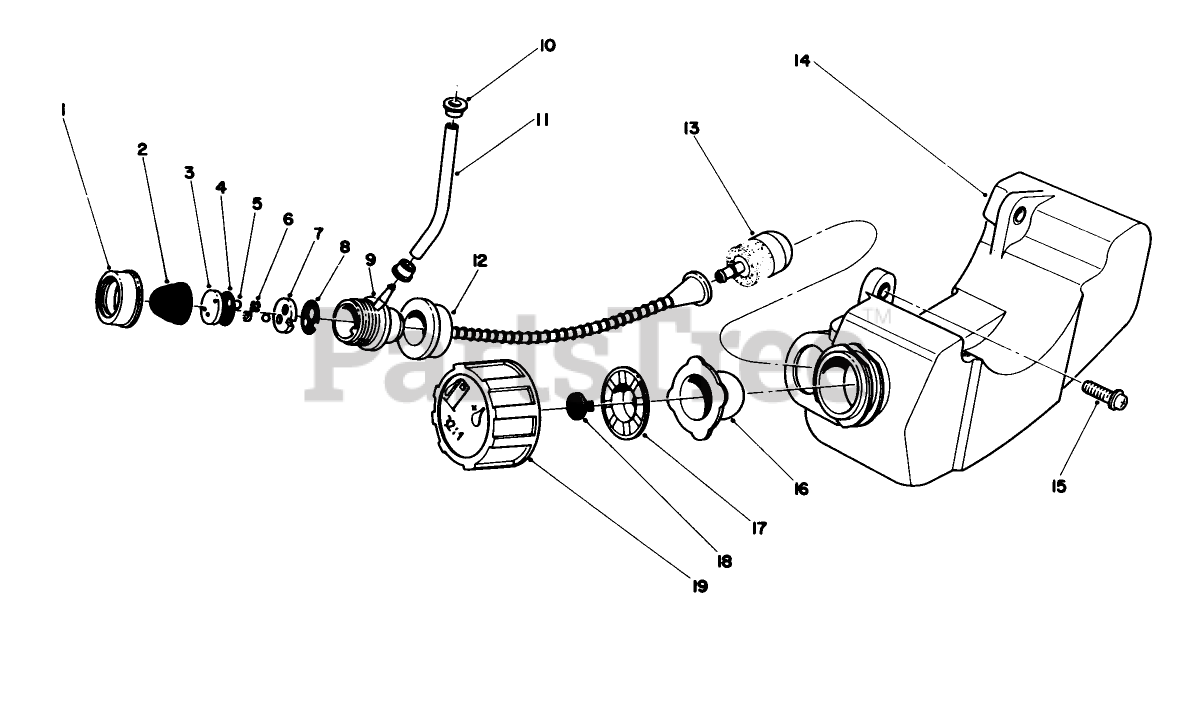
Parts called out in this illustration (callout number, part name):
8	GASKET
9	PRIMER PUMP
13	FUEL FILTER
16	GASKET - PACKING
17	HOLDER
18	BREATHER VALVE
19	TANK CAP
